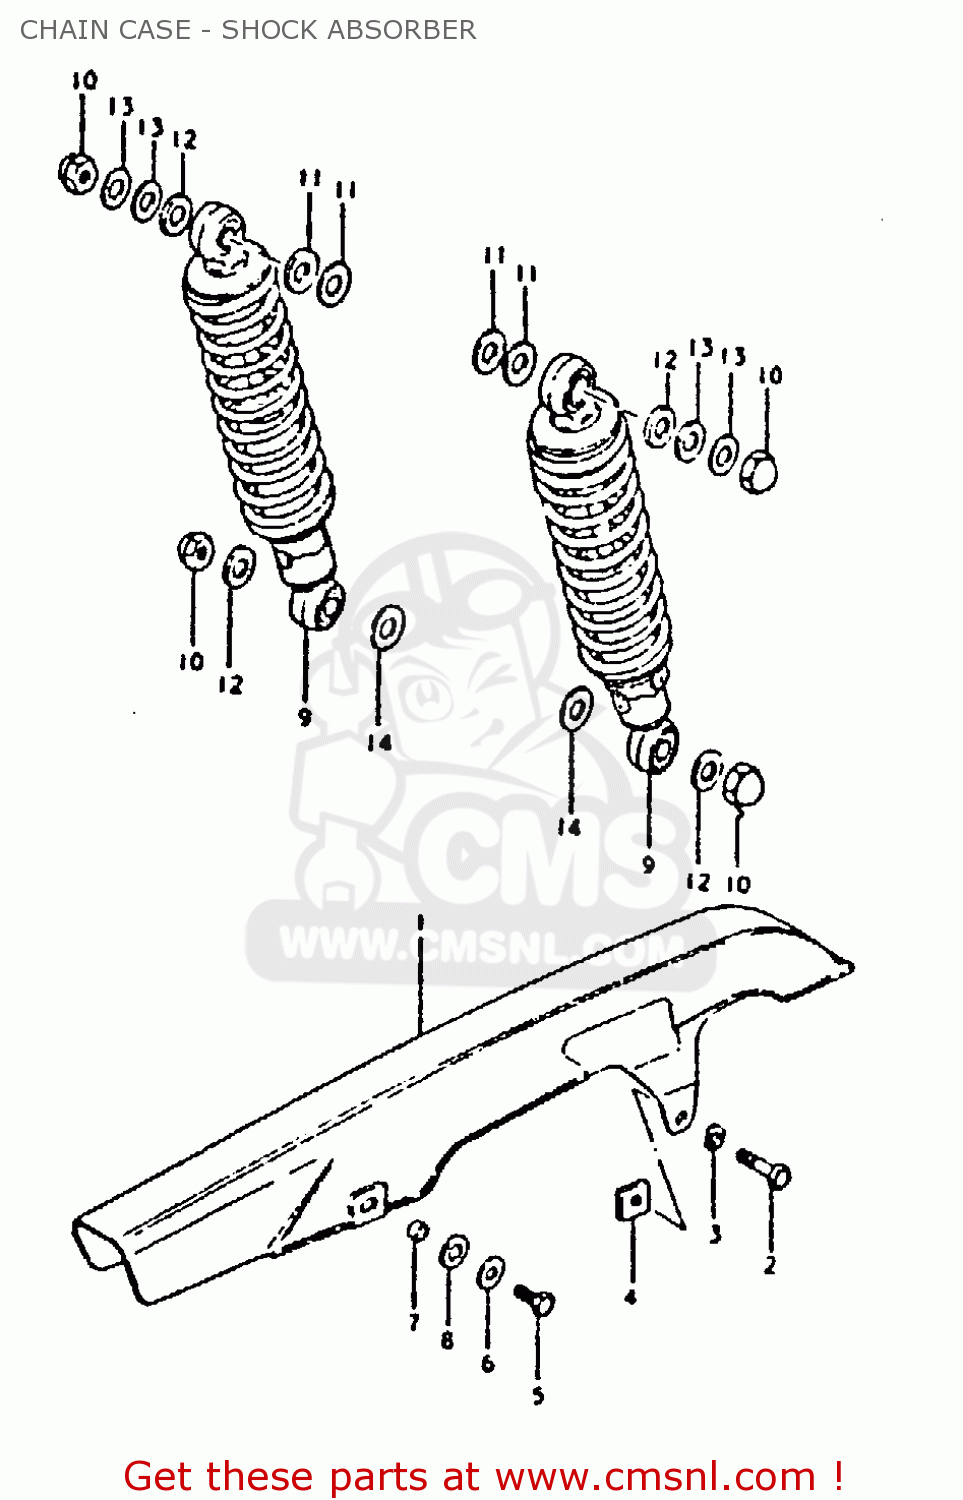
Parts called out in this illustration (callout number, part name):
1	CASE,CHAIN
2	BOLT, UPPER
3	LOCK WASHER
4	NUT,CHAIN CASE RR
5	BOLT
6	WASHER
7	SPACER (6.1X8X5.2)
8	CUSHION
9	ABSORBER ASSEMBLY,REAR SHOCK
10	NUT, LOWER LH
11	WASHER
12	WASHER
13	WASHER(10.5X24X3.2)
14	WASHER (12.5X24X1.6)
